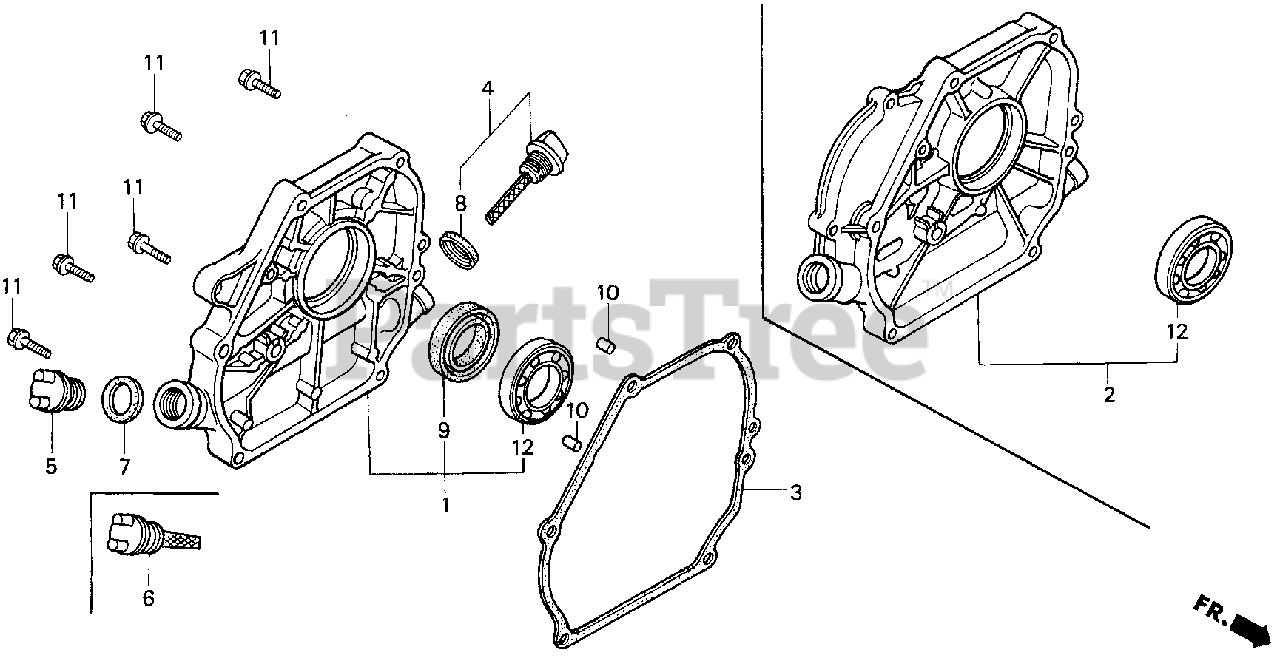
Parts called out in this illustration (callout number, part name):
1	COVER ASSY., CRANKCASE (Q-TYPE)
1	COVER ASSY., CRANKCASE (U-TYPE)
1	COVER ASSY., CRANKCASE
3	GASKET, CASE COVER
3	GASKET, CASE COVER (NON-ASBESTOS)
4	CAP ASSY., OIL FILLER
5	CAP, OIL FILLER
6	CAP, OIL HOLE
7	GASKET, OIL FILLER CAP
8	GASKET, OIL FILLER CAP
9	OIL SEAL (25X41X6)
10	PIN A, DOWEL (8X14)
11	BOLT, FLANGE (8X32)
12	BEARING, RADIAL BALL (6205)
